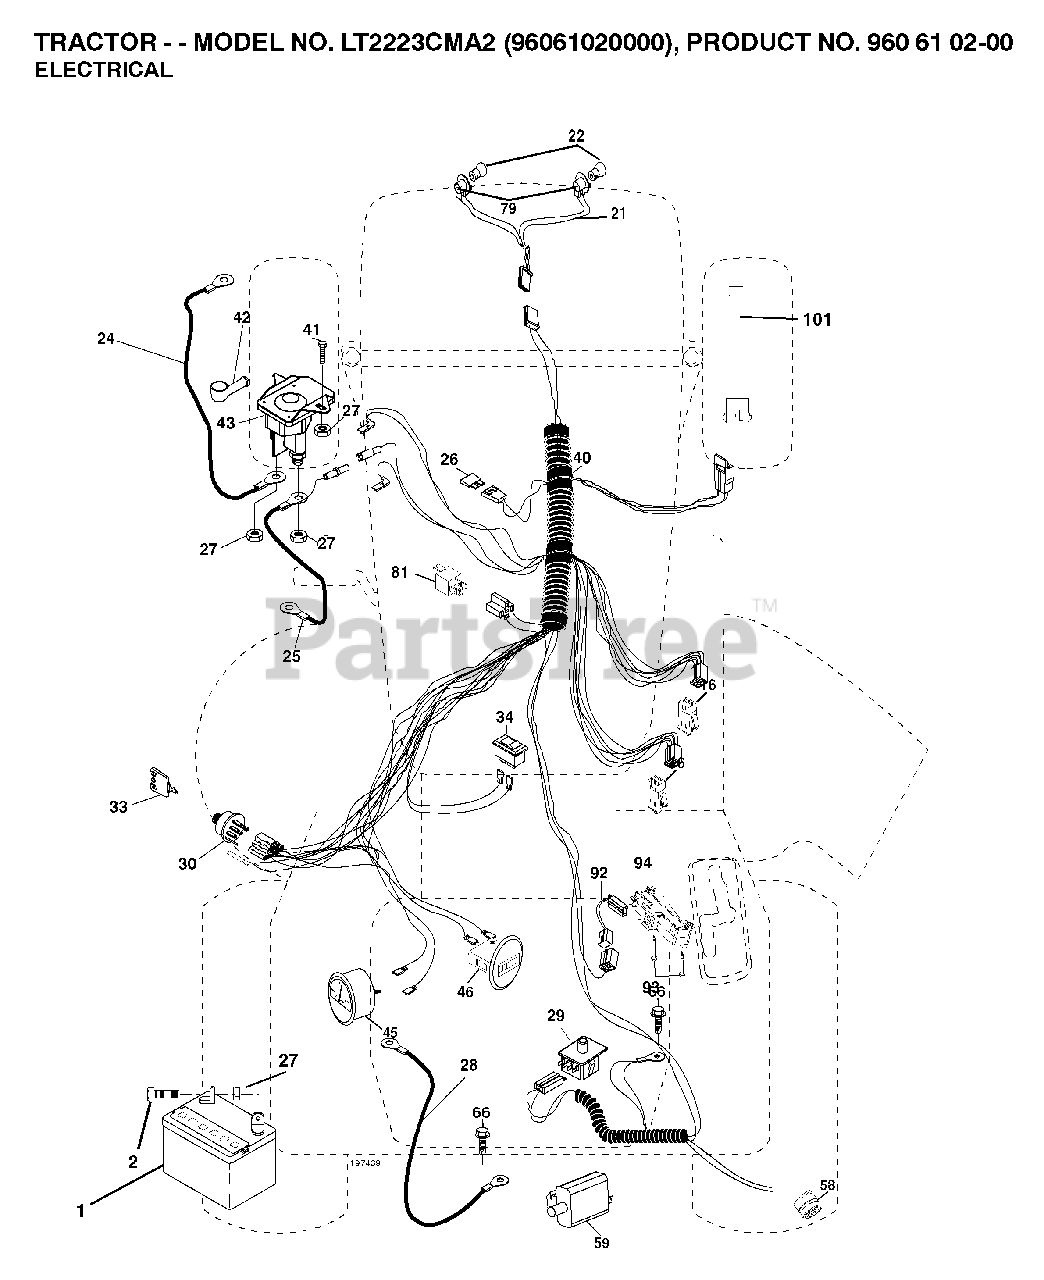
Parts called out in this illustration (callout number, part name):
1	BATTERY 12V .35 AMP
16	SWITCH INTERLOOK PUSH-IN
21	HARNESS.W/LIGHT SOCKET
22	LIGHTBULB
24	BATTERY CABLE GT
25	CABLE BATTERY
26	FUSE 20AMP
27	NUT
28	CABLE GROUND
29	SWITCH.SEAT.DP W/RAMPS
30	SWITCH.IGN.DELTA.W.LGH.ROS
33	KEY MLD GEN DELTA
34	SWITCH LT
42	TERMINAL COVER
43	SOLENOID.W/BRASS.PLUNG
46	HOURMETER SNAP-IN
50	PTO SWITCH
58	BUZZER
79	BULB HOLDER ASM.
81	RELAY.ASSY.T
92	HARNESS.PIGTAIL.CONSLE
93	SCREW.PLASTITE
94	MODULE.REVERSE.ROS
